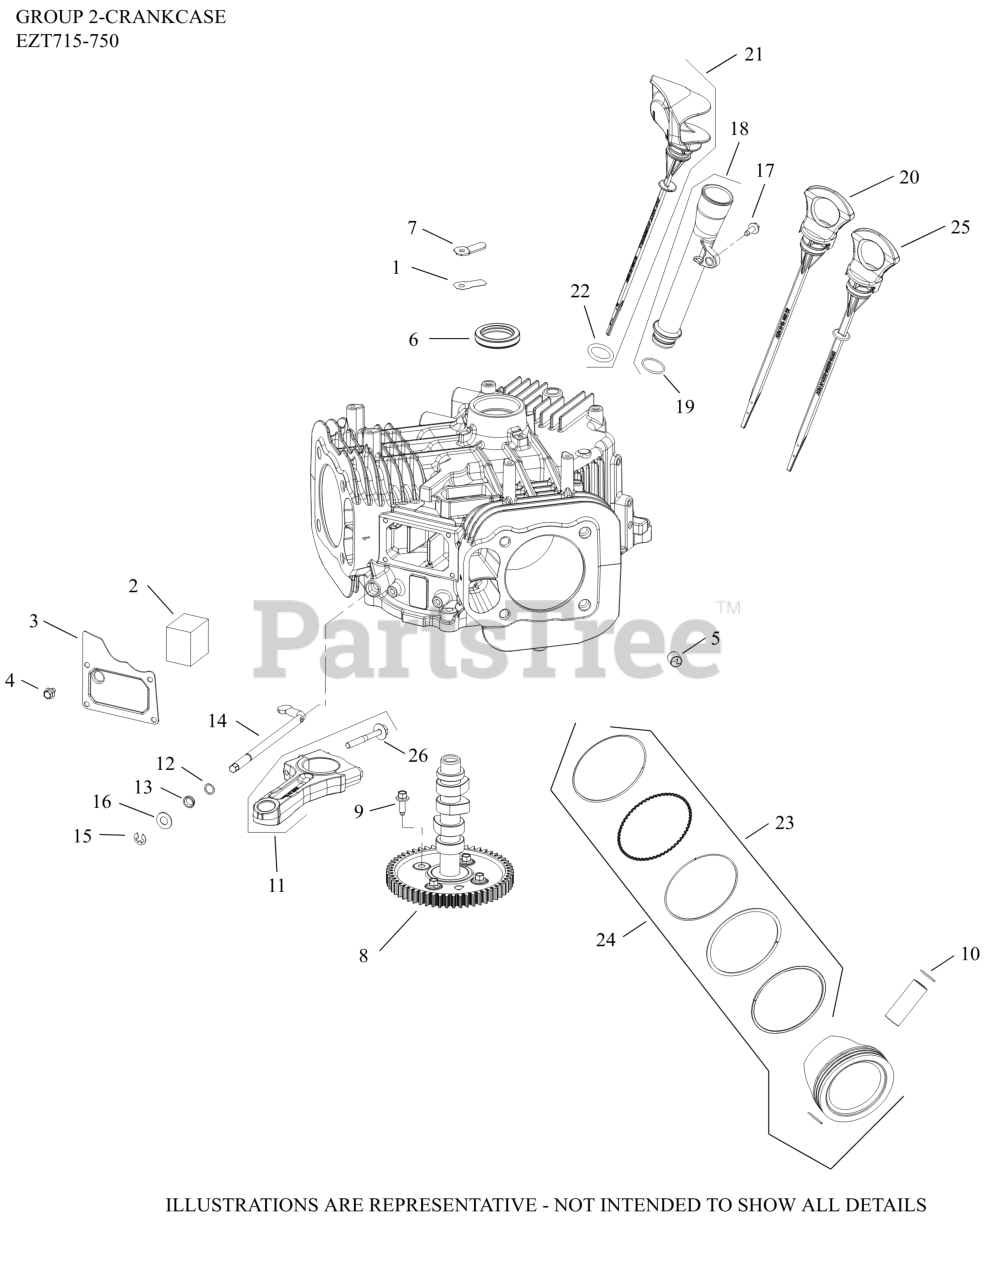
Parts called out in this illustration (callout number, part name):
1	REED, BREATHER
2	FILTER, BREATHER
3	COVER, BREATHER MEDIA
4	SCREW, THREAD FORMING
5	PIN, LOCATING
6	SEAL, OIL (HELIX LIP)
7	RETAINER, REED
8	CAMSHAFT ASSY
10	RETAINER, PISTON PIN
11	ROD, ASSEMBLY CONNECTING
12	WASHER, FLAT 11/32"
13	SEAL, GOVERNOR CROSS SHAFT
14	KIT, CROSS SHAFT
15	CLIP, RETAINER GOVERNOR SHAFT
16	WASHER, FLAT 9 MM
17	SCREW, THREAD FORMING
18	TUBE ASSEMBLY, OIL FILL
20	DIPSTICK, ASSY
23	RING SET(STD)STYLE B-1.2mm Tp RING THICK
23	RING SET(.08)STYLE B-1.2mm RING THICK
23	RING SET(.25)STYLE B-1.2mm Tp RING THICK
23	RING SET(.50)STYLE B-1.2mm Tp RING THICK
24	KIT, PISTON 725CC (STD) STYLE B
24	KIT, PISTON 725CC (.08) STYLE B
24	KIT, PISTON 725CC (.25) STYLE B
24	KIT, PISTON 725CC (.50) STYLE B
26	KIT, ROD BOLTS-(#25086677S)
